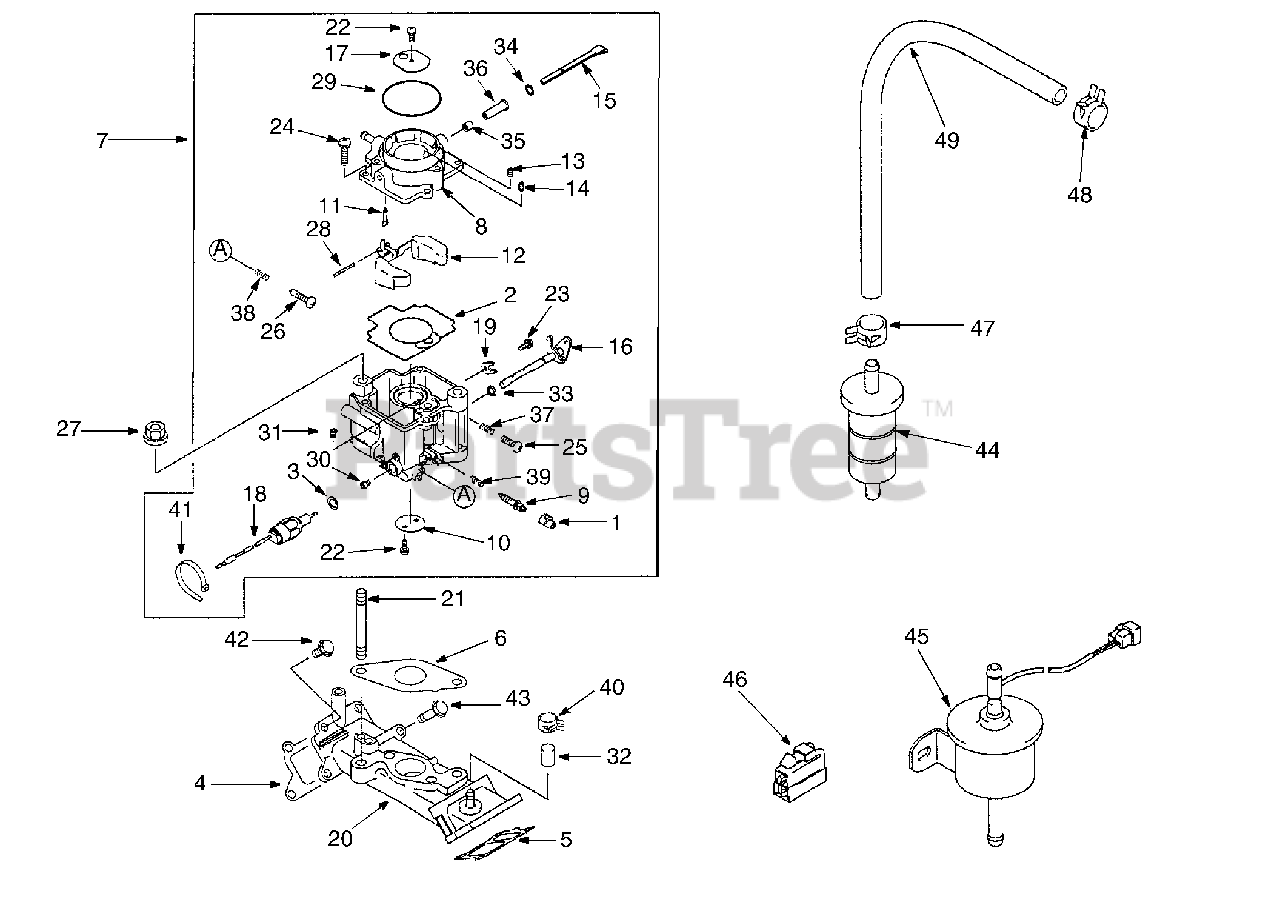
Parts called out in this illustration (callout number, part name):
4	Gasket, Intake Manifold
5	Gasket, Intake Manifold
6	Gasket, Carburetor
7	Carburetor Ass'y
9	Screw, Pilot Air
10	Valve, Throttle
13	Jet, Air, #1.8
14	Jet, Air #0.9
16	Shaft, Throttle
18	Solenoid, Fuel
20	Manifold, Intake
22	Screw, 3 x 5.5
29	O-Ring, 49.4MM
30	Jet, Main #112
31	Jet, Pilot, #58
33	Seal, Throttle Shaft
34	Seal, Choke Shaft
42	Bolt, Flanged 6 x 20
43	Bolt, Flanged 6 x 45
44	Filter, Fuel
46	Connector, Cord
